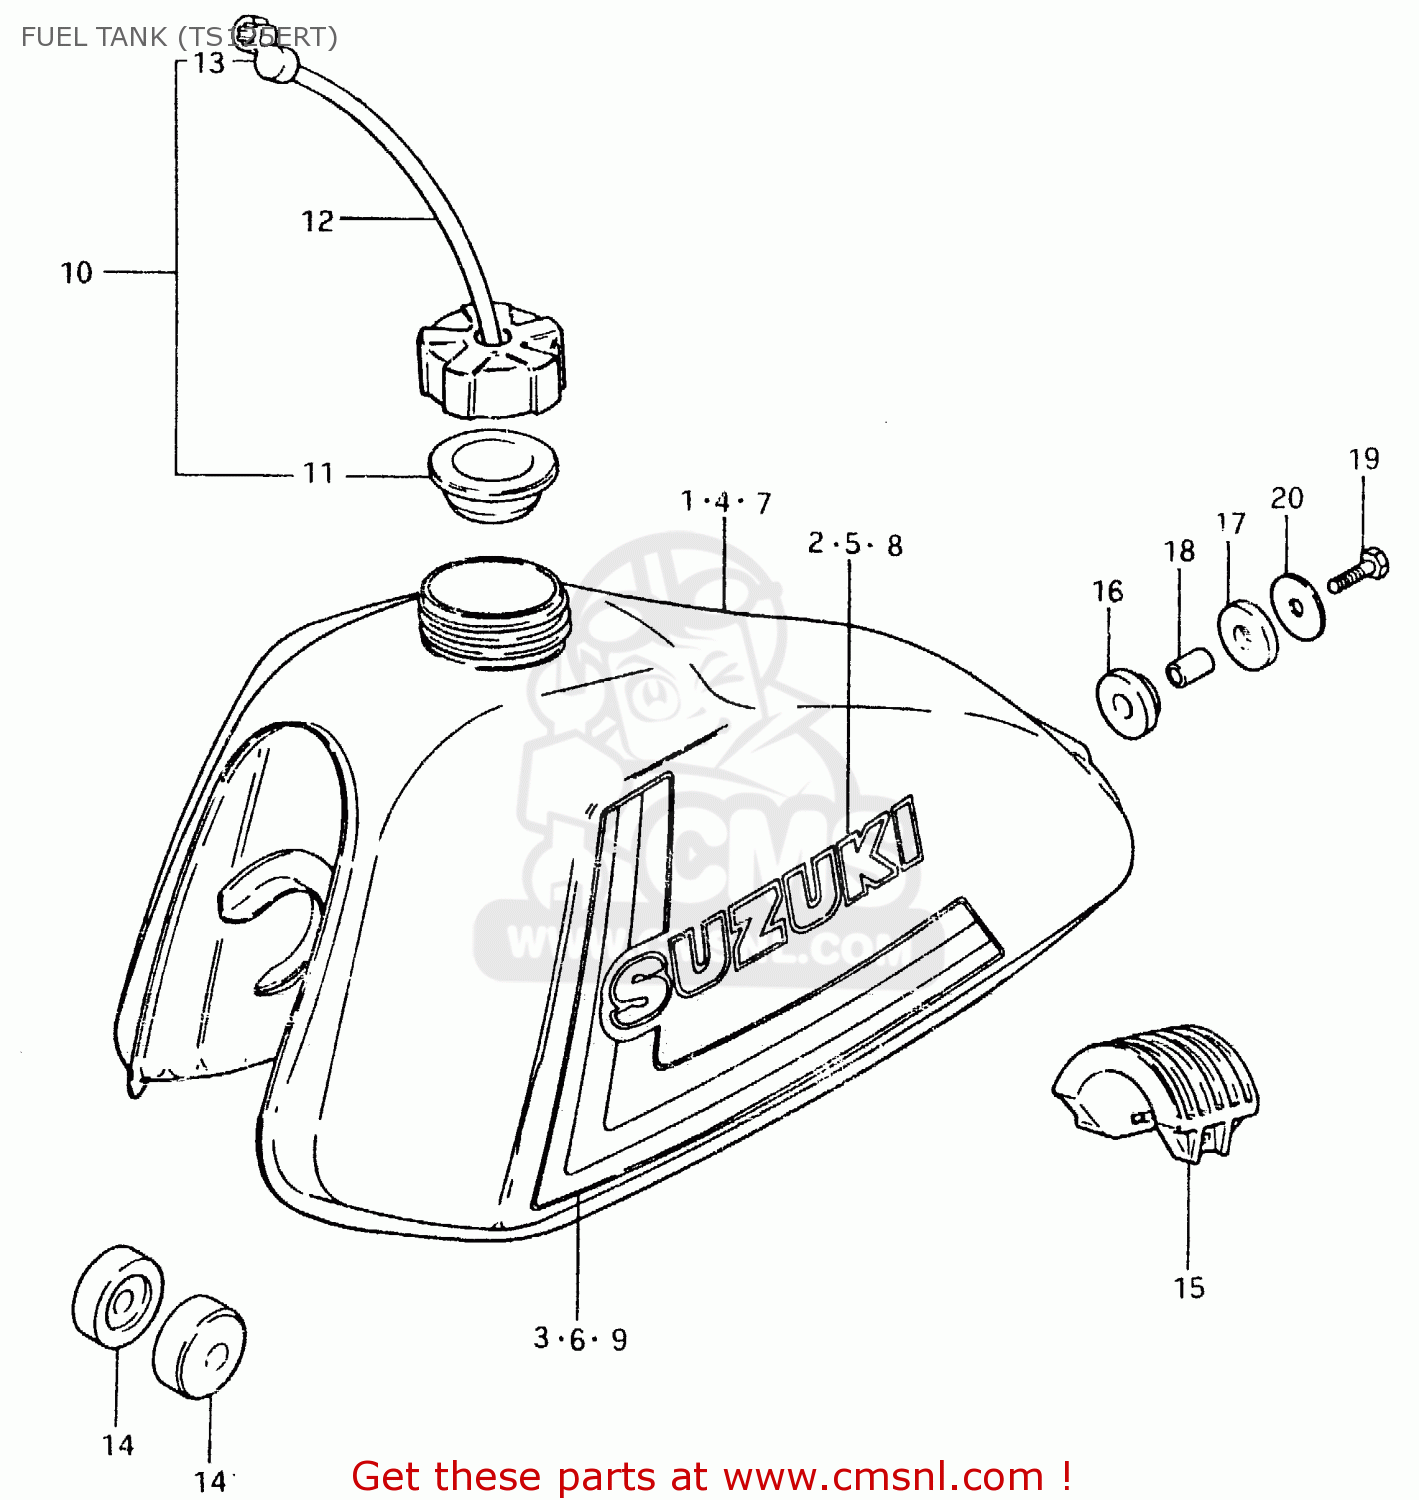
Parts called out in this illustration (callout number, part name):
1	TANK, FUEL (RED)
2	EMBLEM
3	TAPE SET
4	TANK, FUEL (BLUE)
5	EMBLEM
6	TAPE SET
7	TANK, FUEL (WHITE)
8	EMBLEM(BLACK)
9	TAPE SET
10	CAP SET,FUEL TANK
11	GASKET,FUEL TANK CAP (NAS)
12	HOSE
13	CLAMP,FUEL TANK BREATHER HOSE
14	CUSHION
15	CUSHION,FUEL TANK
16	CUSHION
17	CUSHION
18	SPACER(8.5X12X19)
19	BOLT (8X30)
20	WASHER (8.5X29X1.6)
